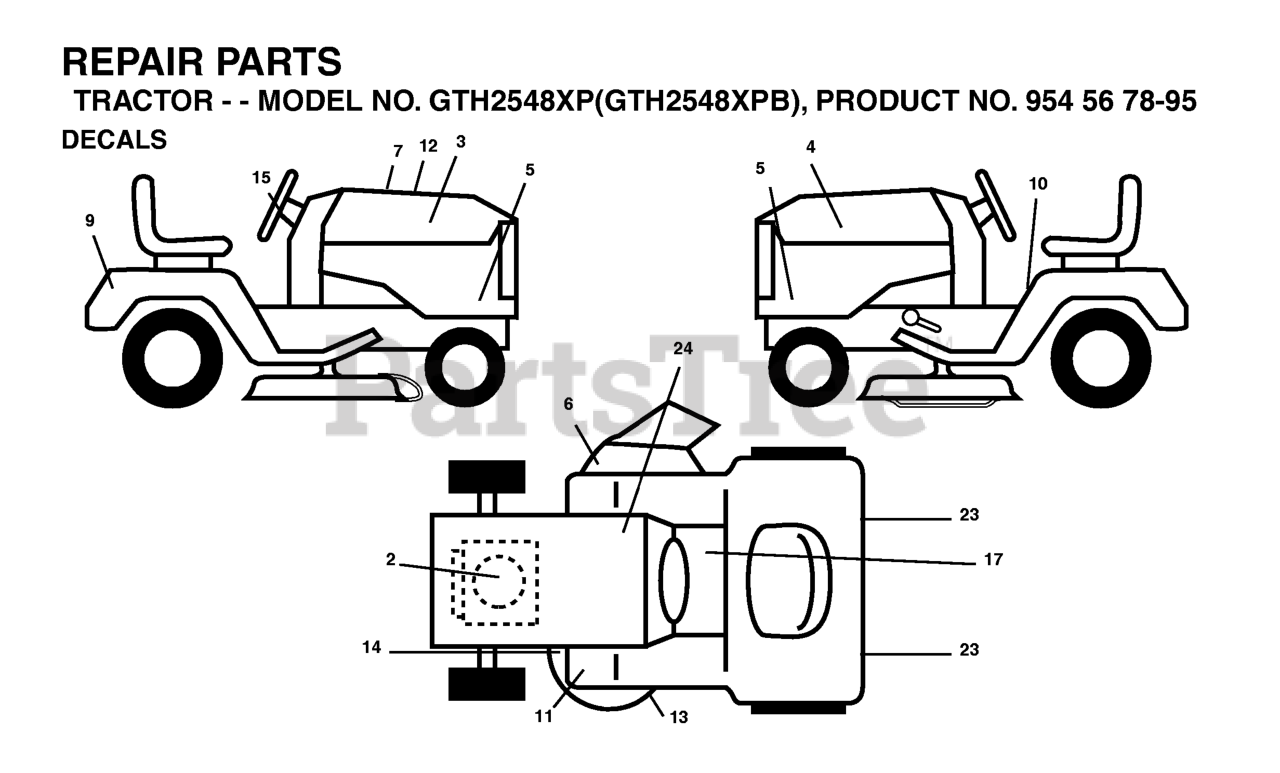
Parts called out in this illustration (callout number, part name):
2	DECAL.ENG.25HP.KAWA.HSQV.XP
3	RH HOOD DECAL
4	LH HOOD DECAL
5	DECAL HOOD SIDES
6	DECAL.WARN.KEEP.HAND.AWAY
9	DECAL, FENDER
10	DECAL FENDER DANGER
11	DECAL, FOOTREST
13	DECAL V-BELT SCHEMATIC
14	DECAL CLUTCH/BRAKE
15	DECAL.WHEEL.STEERING.HUSQ.PERM
23	REFLECTOR-TAIL YT
24	DECAL BTRY SYMBOLS
